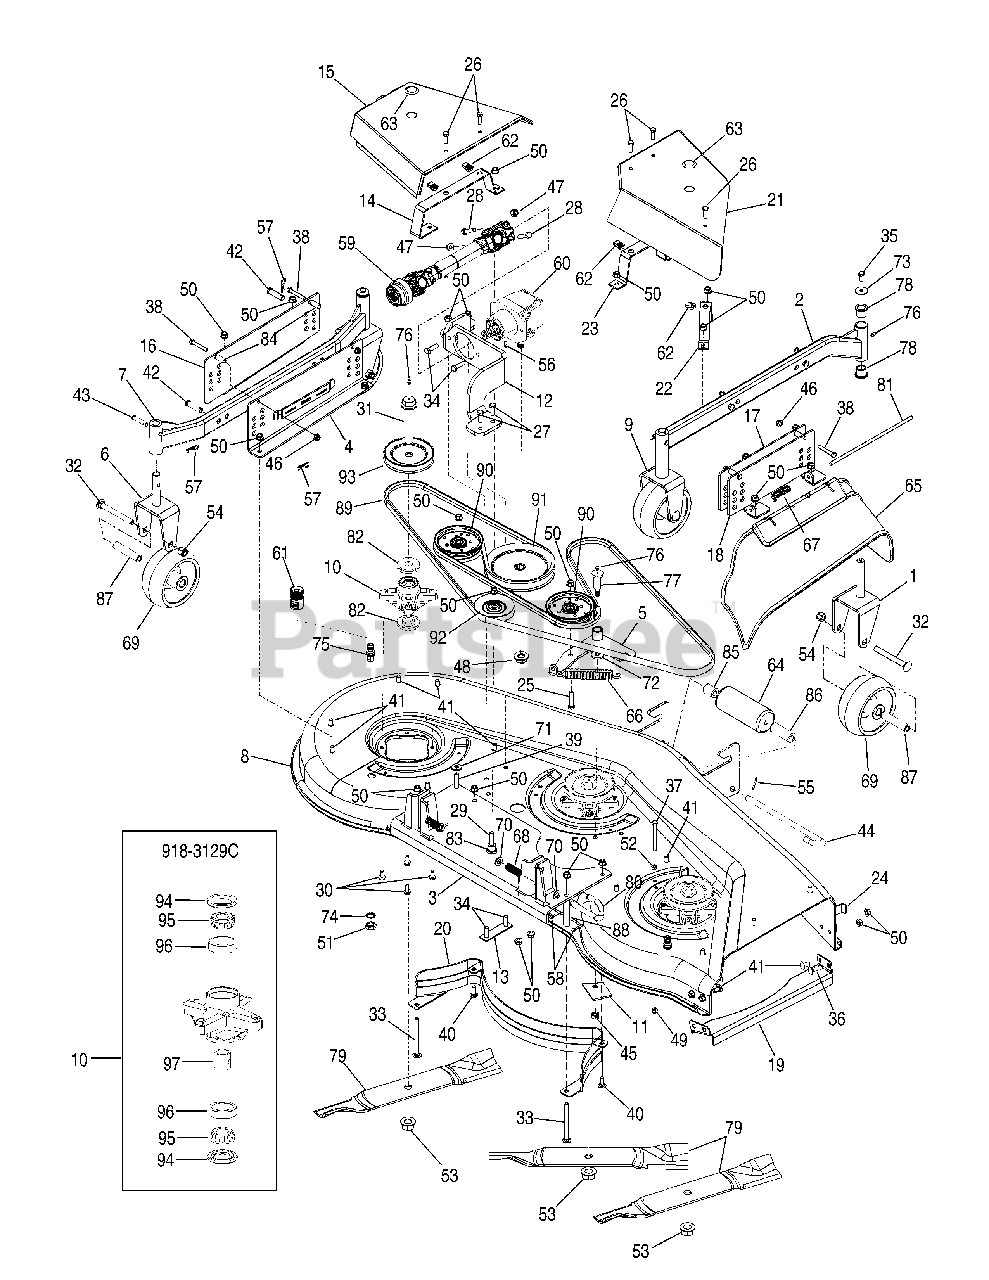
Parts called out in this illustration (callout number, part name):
1	Bracket, Front Caster Wheel
2	Axle, Caster RH
3	Bracket, Rear Deck Hanger
4	Bracket, Wheel Mntg. LH Inner
6	Caster, Rear LH 2.50 Shaft
7	Axle, Caster LH
8	Housing Deck
9	Caster, Rear 4.25 Shaft
10	Spindle Assembly
11	Plate Idler Support
12	Bracket, Gear Box Mounting
13	Plate Gear Box Support
14	Bracket, Belt Cover Mounting
15	Cover, Belt LH
16	Bracket, Wheel Mntg. LH Outer
17	Bracket, Wheel Mntg. RH Inner
18	Bracket, Wheel Mntg, RH Outer
19	Guard Deck Opening
20	Baffle, Rear Deck
21	Cover, Belt RH
22	Bracket, Belt Cover Mounting RH
23	Bracket, Belt Cover Mounting
24	Bracket, Chute Stop 2008 & Before
24	Bracket, Chute Stop 2009 & After
25	Screw, Hex Cap, 3/8-16 x 1.75 Gr5
26	Screw, Hex Cap, 5/16-18 x 1/0 Gr5
27	Screw, Hex Cap, 3/8-16 x 1.0 Gr5
28	Screw, Hex Cap, 3/8-16 x 1.5 Gr5
29	Screw, Hex Cap, 3/8-16 x 2.5 Gr5
30	Screw, Wash. Hd Tapp, 5/16-18 x .75
30	Screw, Wash. Hd Tapp, 5/16-18 x .875
31	Bolt, Spindle, 3/4-16 x 4.25
32	Screw, Carriage, 1/2-13 x 4.5 Gr5
33	Screw, Carriage, 3/8-16 x 4.50 Gr5
34	Screw, Hex Cap, 3/8-16 x 1.25 Gr5
35	Screw, Hex Cap, 5/16-18 x .75 Gr5
36	Bolt Carriage, 3/8-16 x 1.25
37	Screw, Hex cap, 5/16-18 x 3.25 Gr5
37	Screw, Hex cap, 3/8-16 x 3.0 Gr8
38	Screw, Hex Cap, 5/16-18 x 2.0 Gr5
39	Screw, Hex cap, 3/8-16 x 2.0 Gr5
40	Bolt, Carriage, 3/8-16 x 1.0
41	Bolt, carriage, 3/8-16 x .75
43	Pin, Clevis, .375 x 1.75
44	Pin, Roller, 1/2 x 11.06
45	Nut, Hex Lock, 7/16-14
46	Nut, Hex Insert Flange Lock, 5/16-18 GrF
47	Nut, Hex Insert Jam Lock, 3/8-16 Gr5
48	Nut, Hex Flange, 5/8-18
49	Nut, Hex Insert Lock, 5/16-18 Gr5
49	Nut, Hex Insert Lock, 3/8-16 Gr8
50	Nut, Hex Flange lock, 3/8-16 GrF
51	Nut, Hex, M16 - 1.5
52	Nut, Hex Jam Lock, 5/16-18
52	Nut, Hex Jam Lock, 3/8-16 Gr5
53	Nut, hex Flange Lock, 3/4-16 Gr8
54	Nut, Hex Insert Lock, 1/2-13 GrB
55	Pin, Cotter, 1/8 x 1.0
56	Key, Hi Pro, 3/16 x 3/4
57	Pin, Internal Cotter, 3/16 x 1.0
58	Pin, Cotter
59	Shaft, Deck Drive
59	Repair Kit, Yoke Lock
61	Adapter Nozzle
62	Nut, Speed, 5/16-18
63	Button, Plug
64	Roller, Front
65	Deflector Chute
66	Spring, Extension, 1.0 x 6.14
67	Spring, Torsion
68	Spring Compression, .57 x 2.09
69	Wheel, Caster
70	Washer, Flat, .535 x .93 x .09
71	Washer, Flat, .385 x 1.0 x .135
72	Washer, Flat, .45 x 1.25 x .164 HT
73	Washer, Flat, .33 x 1.25 x .06 HT
74	Washer, Lock
75	Nozzle, Deck wash
76	Fitting, Lube
77	Bolt, Shoulder, .68 x 1.59:7/16-14
78	Bearing, Flange, .75ID
79	Blade High-Lift
80	Rod, Deck Release
81	Rod, Chute Deflector
82	Spacer, Spindle
83	Spacer, Shoulder, .385 x .785 x .54
84	Spacer, .35 x 1.03
85	Spacer, .51 x 1.16
86	Spacer, .51 x 2.5
87	Axle, Caster Wheel
88	Spacer, .505 x .5 x 3.31
89	V-Belt, B Section x 157
90	Pulley Idler 4.25
91	Pulley, Drive
92	Pulley, V Idler 4.0 Dia
93	Pulley, Spindle
94	Seal, Oil
95	Bearing, Cone
96	Cup, Bearing
97	Spacer, Bearing
